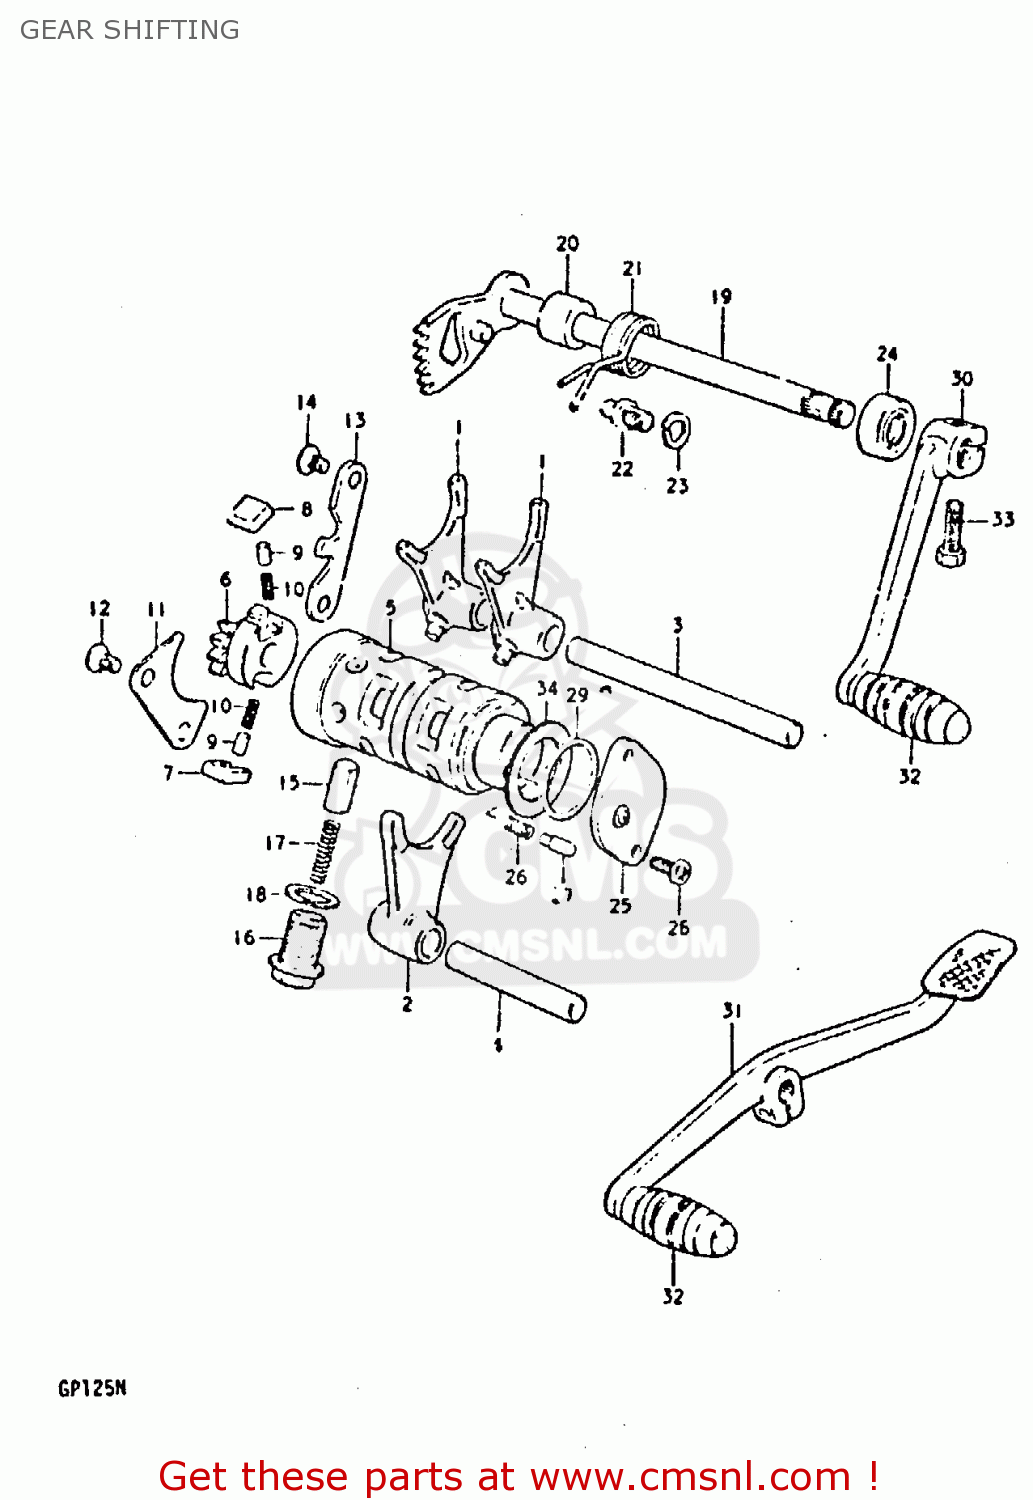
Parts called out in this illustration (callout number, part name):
1	FORK,GEAR SHIFT NO.1
2	FORK,GEAR SHIFT NO.2
3	SHAFT,GEAR SHIFT FORK
4	SHAFT,GEAR SHIFT FORK
5	CAM,GEAR SHIFT
6	RETAINER,GEAR SHIFT CAM
7	PAWL,GEAR SHIFT NO.1
8	PAWL,GEAR SHIFT NO.2
9	PIN(5X8)
10	SPRING
11	LIFTER,GEAR SHIFT PAWL
12	SCREW
13	GUIDE,GEAR SHIFT CAM
14	SCREW
15	STOPPER,GEAR SHIFTING
16	BOLT,GEAR SHAFT CAM STOPPER
17	SPRING
18	GASKET(14X19.2X2) (NAS)
19	SHAFT,GEAR SHIFT
20	SPACER(12X20X15.3)
21	SPRING
22	STOPPER,GEAR SHIFT CAM
23	LOCK WASHER
24	OIL SEAL
25	BODY,GEAR SHIFT SWITCH
26	SPRING
27	PIN(5X15.5)
28	SCREW
29	O-RING (D:2.4 ID:26.2)
30	LEVER ASSY,GEAR SHIFT
32	RUBBER,GEAR SHIFT PEDAL
33	BOLT
